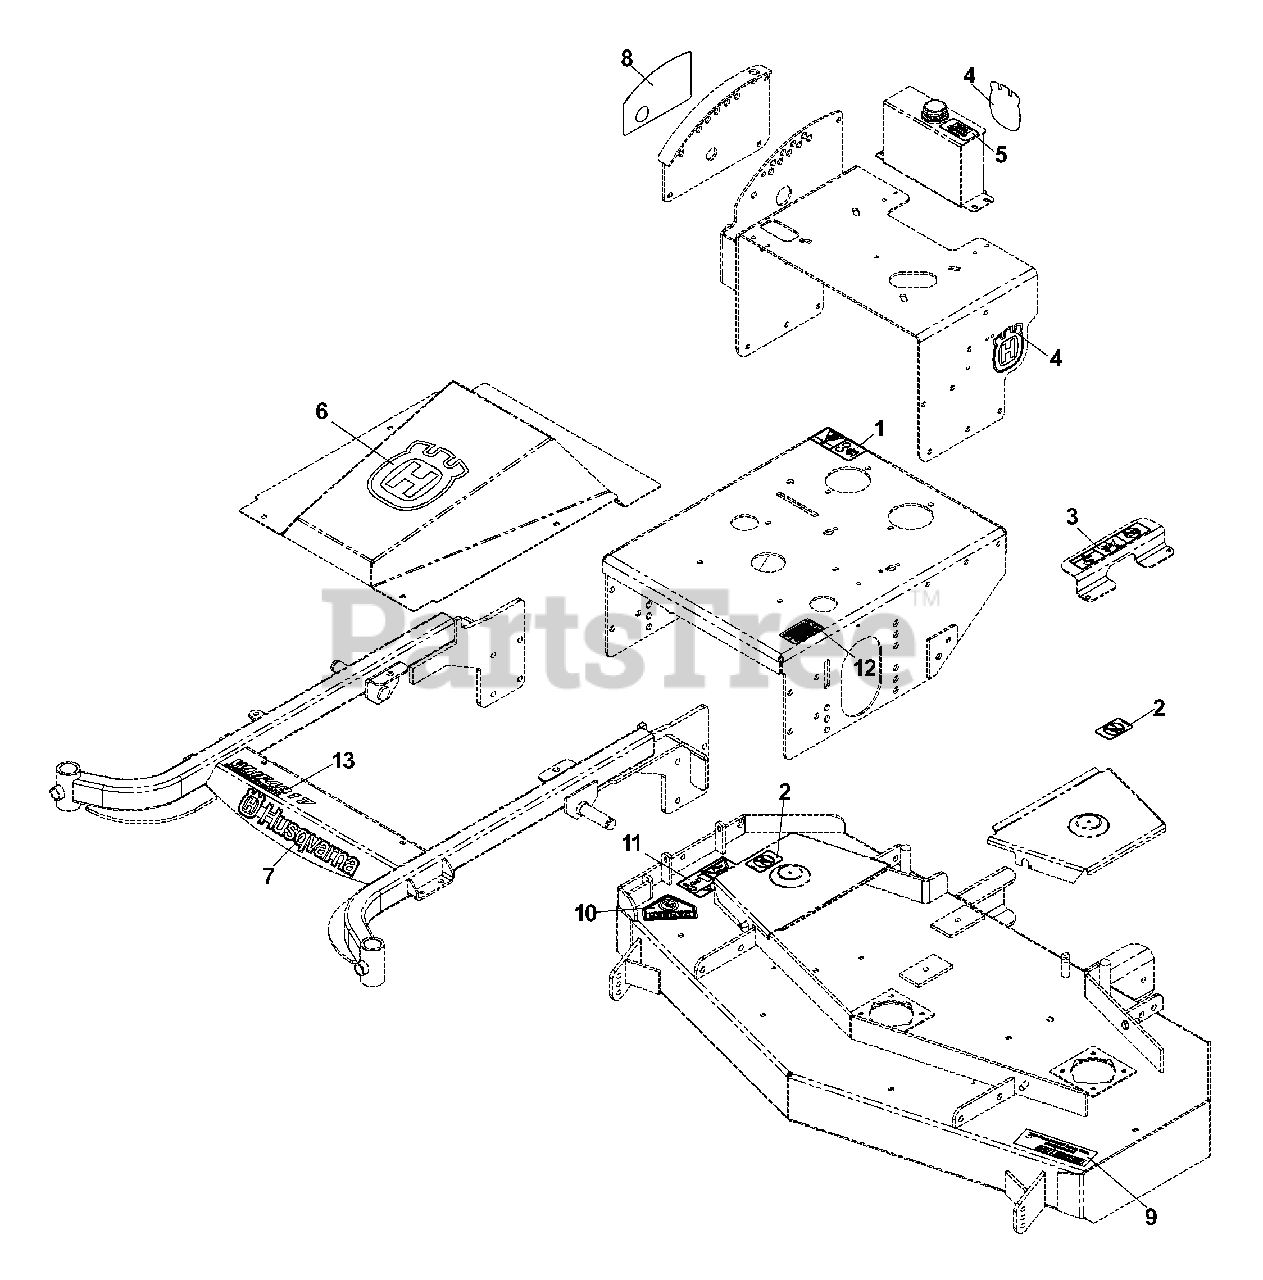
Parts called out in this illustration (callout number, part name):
1	DECAL, EURO DANGER, BELT DRIVES
2	DECAL, EURO NO STEP
3	DECAL, EURO BATTERY WARNING
4	DECAL, SMALL CROWN
5	DECAL, MOBIL
6	DECAL, CROWN
7	DECAL, HUSQVARNA
8	DECAL, CUT HEIGHT
9	DECAL, NASCAR
10	DECAL, CPSC
11	DECAL, EURO SEVERING
12	DECAL, PROP 65
13	DECAL, WHF4817
13	DECAL, WHF5219
